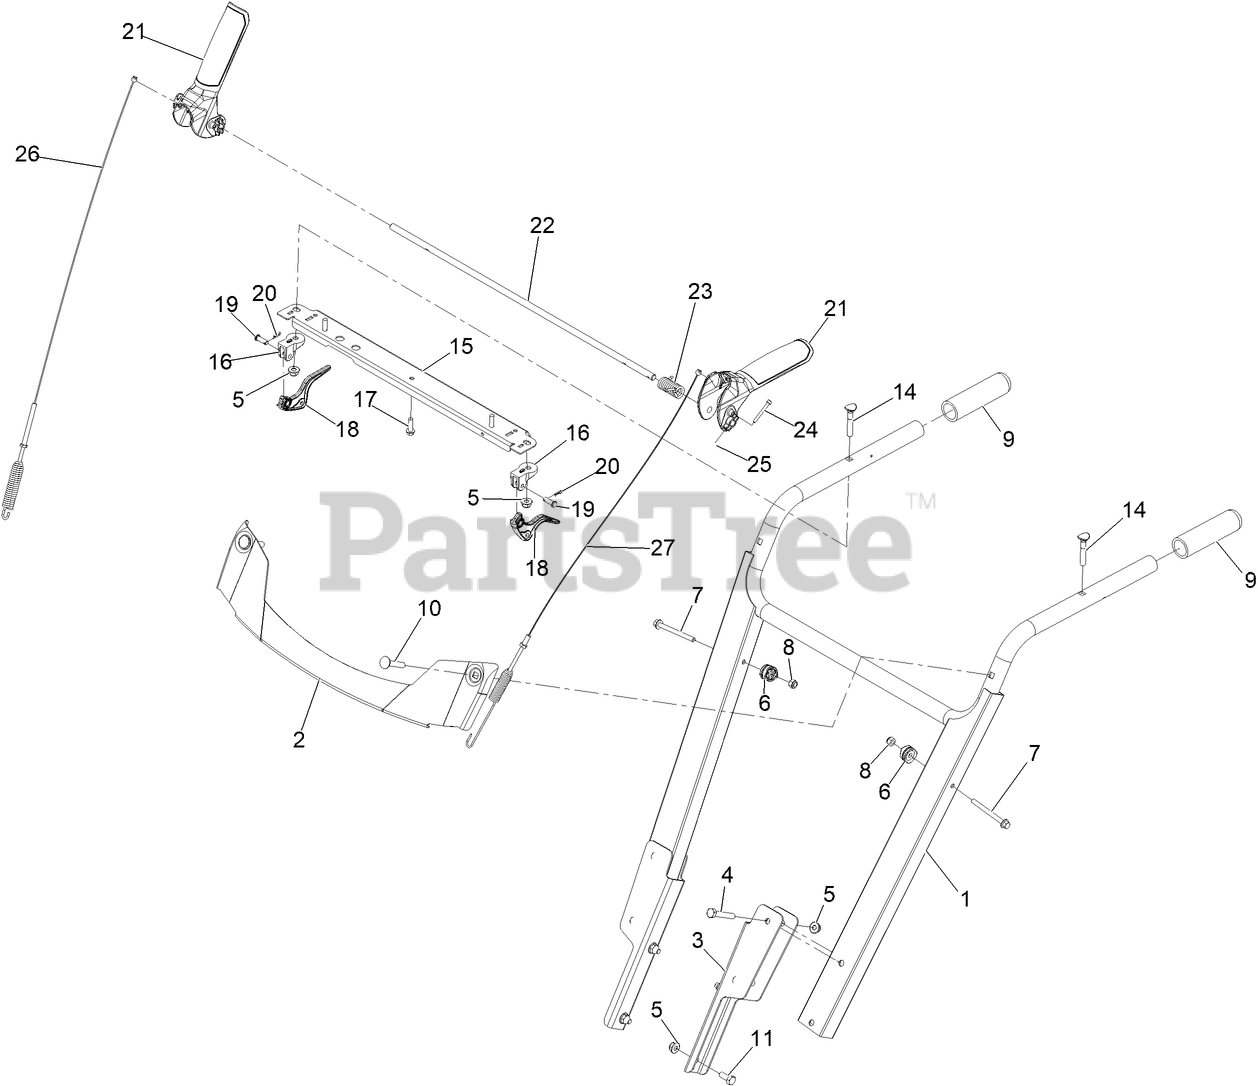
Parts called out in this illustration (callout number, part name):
1	HANDLE ASM HD, WELDED
2	METAL TRIM, HD
3	BRACKET-HANDLE, LOWER
4	SCREW-HH
6	CLAMP-CABLE
7	SCREW-HHF
8	NUT-HEX
9	GRIP-HANDLE
10	BOLT-CARR
11	SCREW-HH
14	SCREW-HANDLE
15	BRACE-CONSOLE
16	MOUNT-LEVER, CLUTCH
17	SCREW-PLASTITE, HWH
18	LEVER-CLUTCH
19	PIN-CLEVIS
20	PIN-HAIR
21	LEVER-CONTROL
22	Rod-Lockout
23	SPRING-TORSION, HANDLE RETURN
24	SCREW-HSH M4-0.7 X 36MM
25	NUT-HEX NYL INS M4-0.7
26	CABLE-AUGER
27	CABLE-TRACTION
